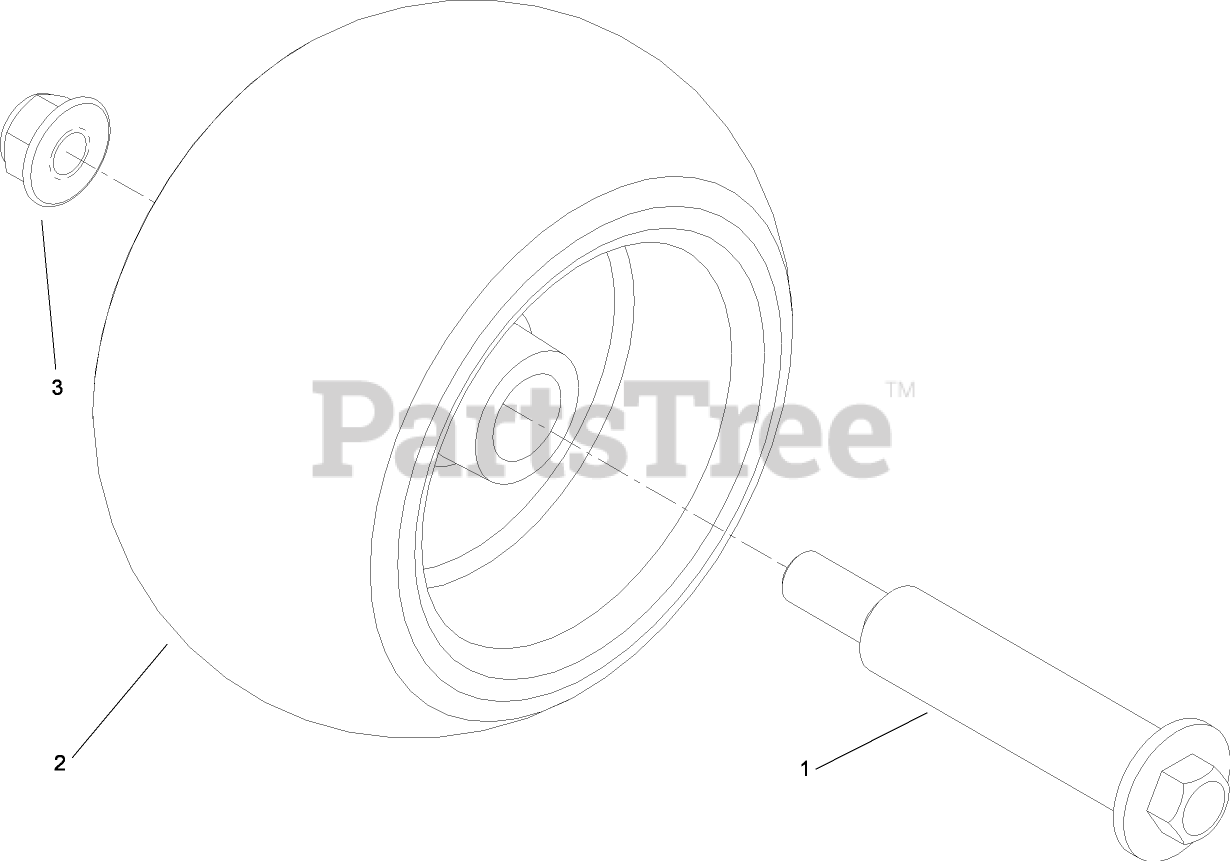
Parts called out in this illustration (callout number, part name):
1	BOLT-SHOULDER
2	ROLLER-SCALP, ANTI
3	NUT-HF, NI
